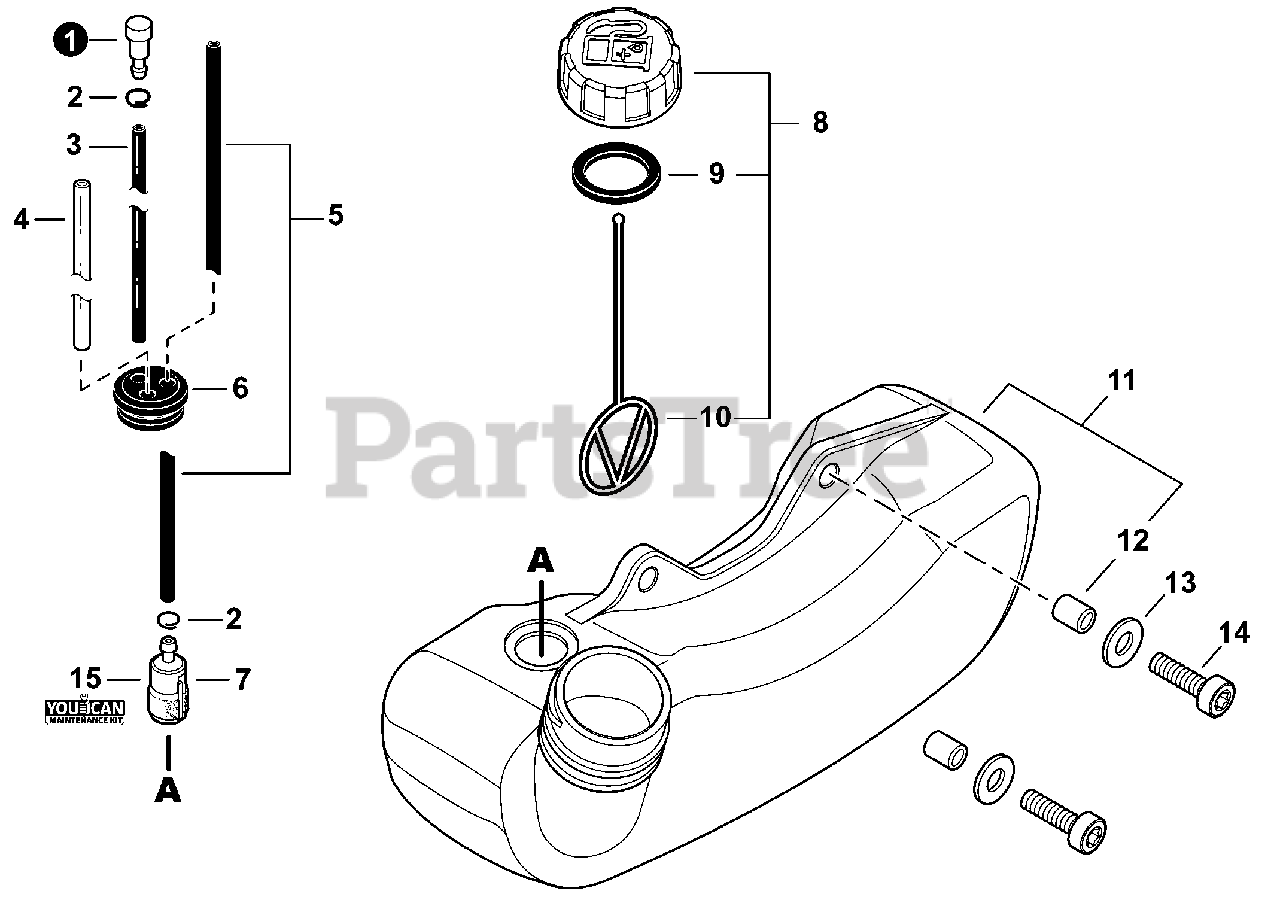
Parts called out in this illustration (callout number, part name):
1	VENT ASSY
2	CLIP 6 MM
3	PIPE, FUEL 3×5×80 BLACK
4	PIPE, FUEL 3×6×85 CLEAR
5	PIPE, FUEL 3×5×210 BLACK
6	GROMMET, FUEL Ø5
7	FILTER, FUEL
8	CAP ASSY, FUEL
9	GASKET, FUEL CAP
10	CONNECTOR, CAP L= 100 MM
11	TANK ASSY, FUEL
12	SPACER 6.2×7.8×6
13	WASHER 5.5×12×0.8
14	BOLT, TORX 5×16
15	TUNE-UP KIT - YOUCANT
